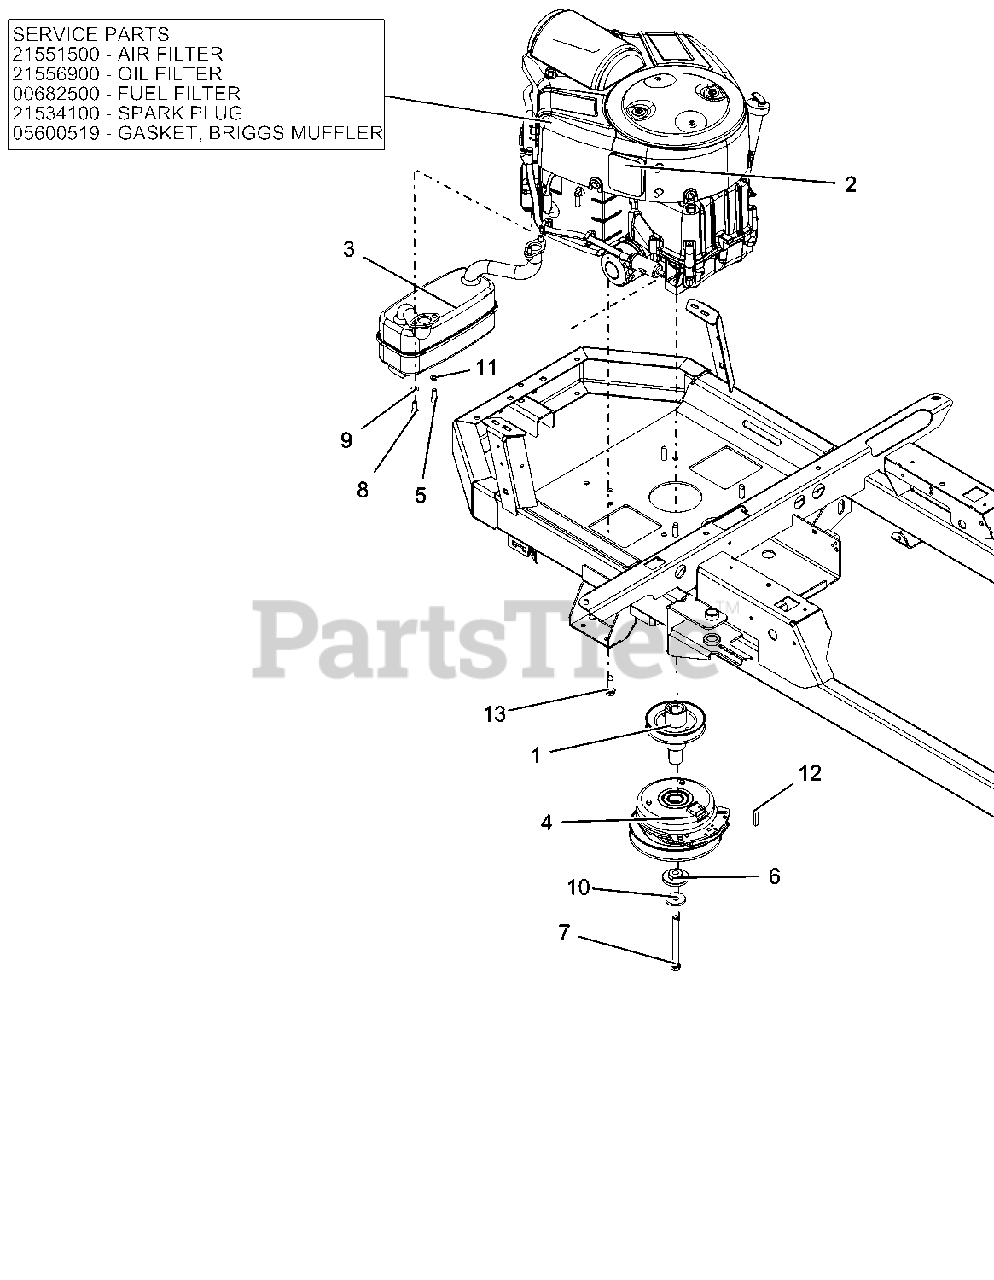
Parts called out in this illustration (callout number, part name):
1	WLDMT,DRIVE SHEAVE-X BRIGGS BL
2	PLUG, SPARK
2	FILTER, BRIGGS AIR
2	OIL FILTER, BRIGGS
2	GASOLINE FILTER, BRIGGS
2	GASKET, MUFFLER BRIGGS 690970
2	ENGINE, B&S 22HP IKON
3	MUFFLER ASSEMBLY
4	CLUTCH,105FTLB MONOPOLE 6.83"
5	SCR-CAP .31-18X.75 S/HD
6	BSHG-FLG .469X1.06X.574X2.0
7	BLT-HEX.438-20X4.5GR8YZ NYTORQ
8	SCR-CAP .31-18X.75 S/HD
9	@WSHR-LK .31X.078 REG YWZC
10	WASHER, 7/16" SPRING DISK
11	@WSHR-LK .31X.078 REG YWZC
12	KEY-SQ .25 X 1.25 X .25 SAE
13	@SCR-TAP .38-16X1.25 HWH TR YZ
